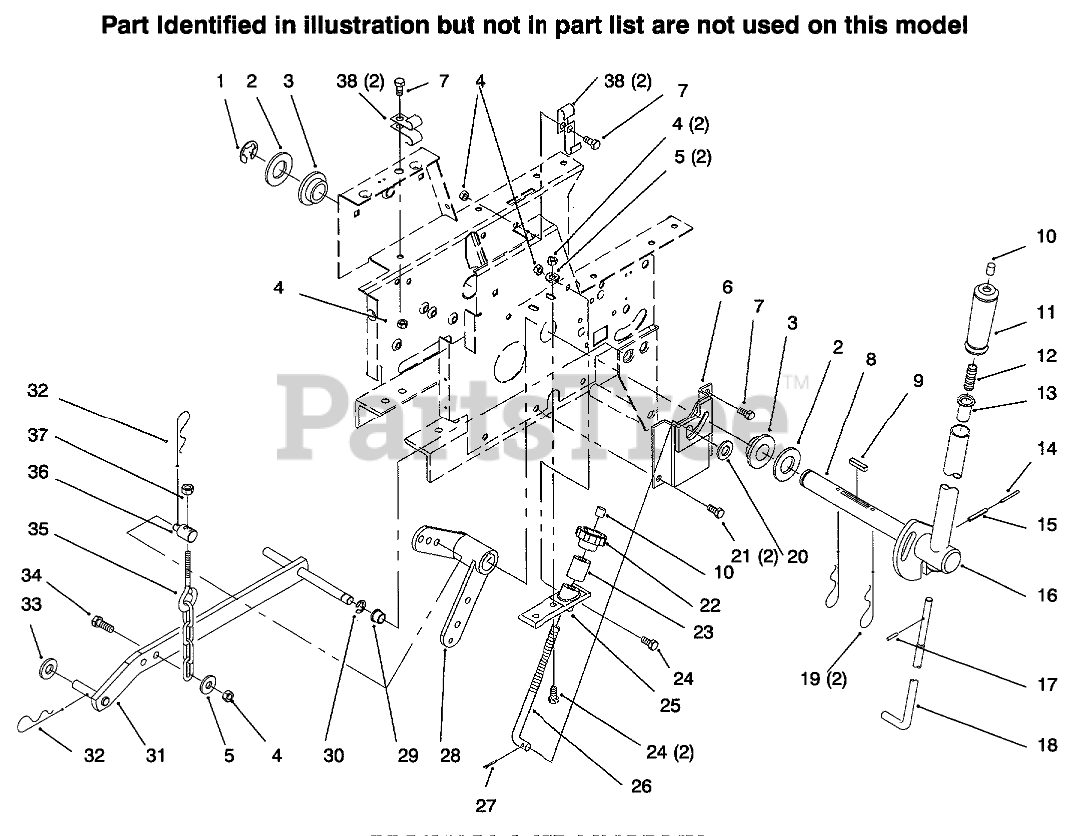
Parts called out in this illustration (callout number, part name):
1	RING-RETAINING
2	WASHER-FLAT
3	BEARING-FLANGE
4	NUT-LOCK, NI
5	WASHER-PLAIN
6	Latch Bracket
7	Bolt
8	SHAFT-LIFT LEVER
9	KEY-SQUARE
10	CAP-ROD, PLUNGER
11	GRIP-HANDLE
12	SPRING-COMPRESSION
13	RETAINER-SPRING
14	PIN-SPRING
15	PIN-ROLL
16	Lift Lever
17	PIN-SPIROL
18	ROD-LATCH LIFT
19	PIN-HAIR
21	WASHER-FLAT
21	SCREW-SELF TAP
22	KNOB-LIFT CONTROL
23	Sleeve
24	SCREW-HH
25	Casting
26	ROD-HEIGHT CONTROL
27	PIN-COTTER
28	Lift Lever
29	BUSHING
30	RING-RETAINING, EXTERNAL
31	Bar-Lift
32	PIN-HAIR
33	WASHER-FLAT
34	SCREW-HH
35	CHAIN-LIFT
36	TRUNNION-LIFT
37	NUT-LOCK, NI
38	CLIP
39	SCREW-HH
